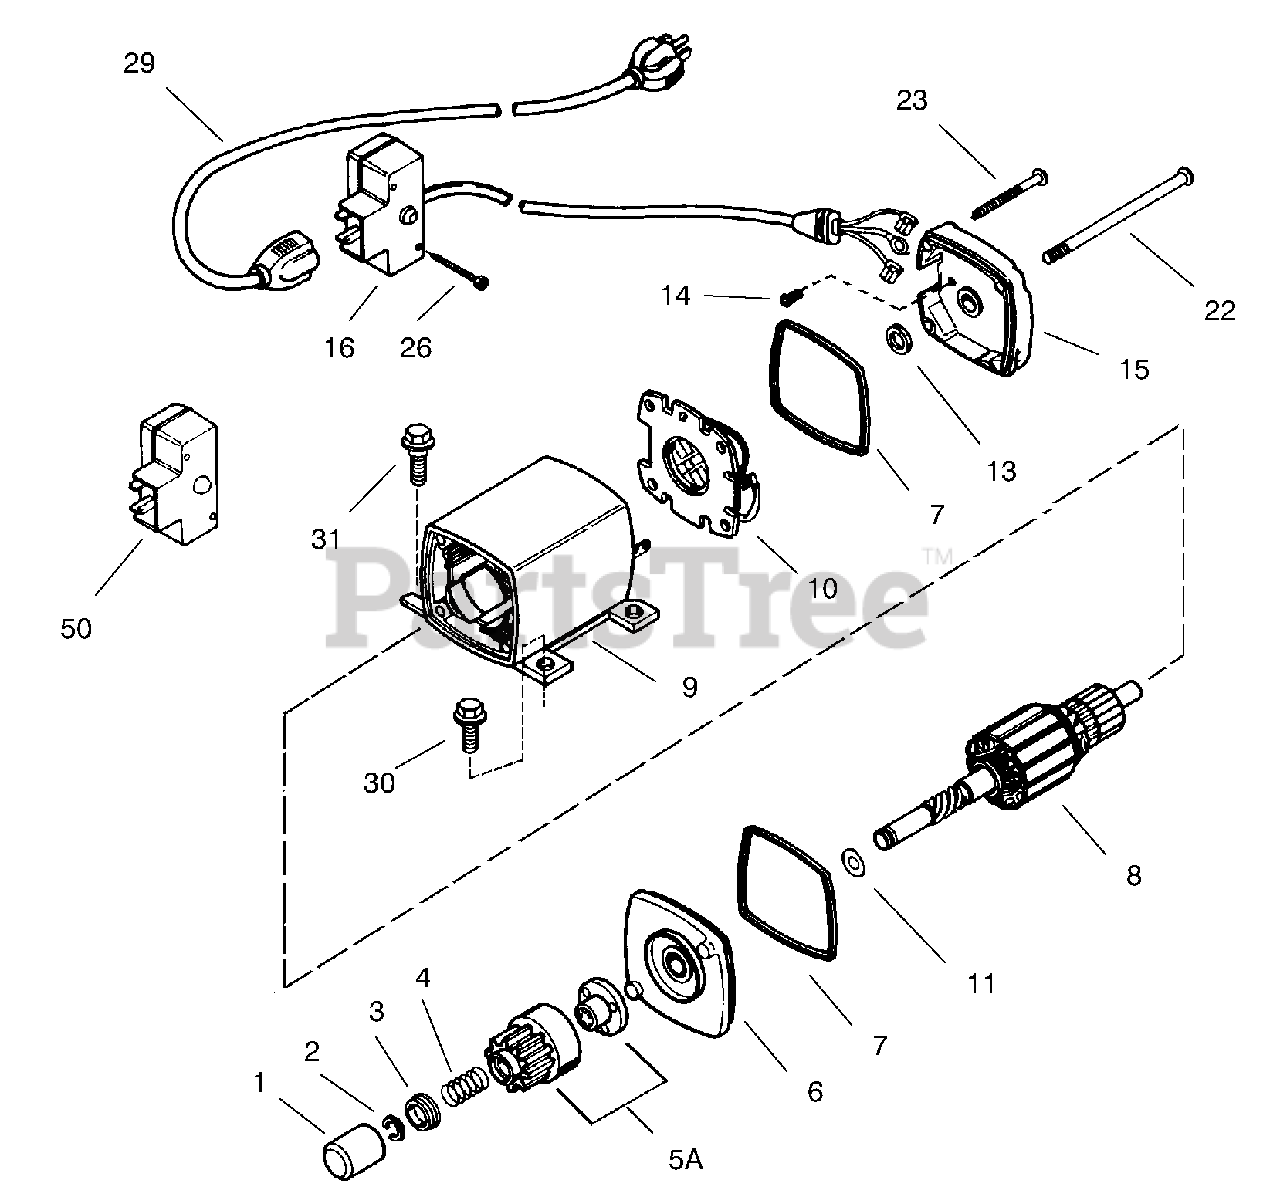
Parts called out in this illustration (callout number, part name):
1	Dust Cover
2	Retainer Ring
3	Spring Retainer
4	Anti-drift Spring
5A	Gear and Nut (Incl. Ref.# 2)
6	Drive End Cap Asm. (Incl. Ref.# 7)
7	O-Ring
8	Armature
9	Housing Assembly
10	Brush Card Assembly
11	Thrust Washer
13	Thrust Washer
14	Ground Screw
15	Commutator End CapAsm.(Incl. Ref.# 7)
16	Switch Box Assembly (Incl. Ref# 26)
22	Case Bolt
23	Ground Screw
26	Screw
29	Extension Cord
30	Screw-Torx
31	Screw
50	Switch Repair Kit
